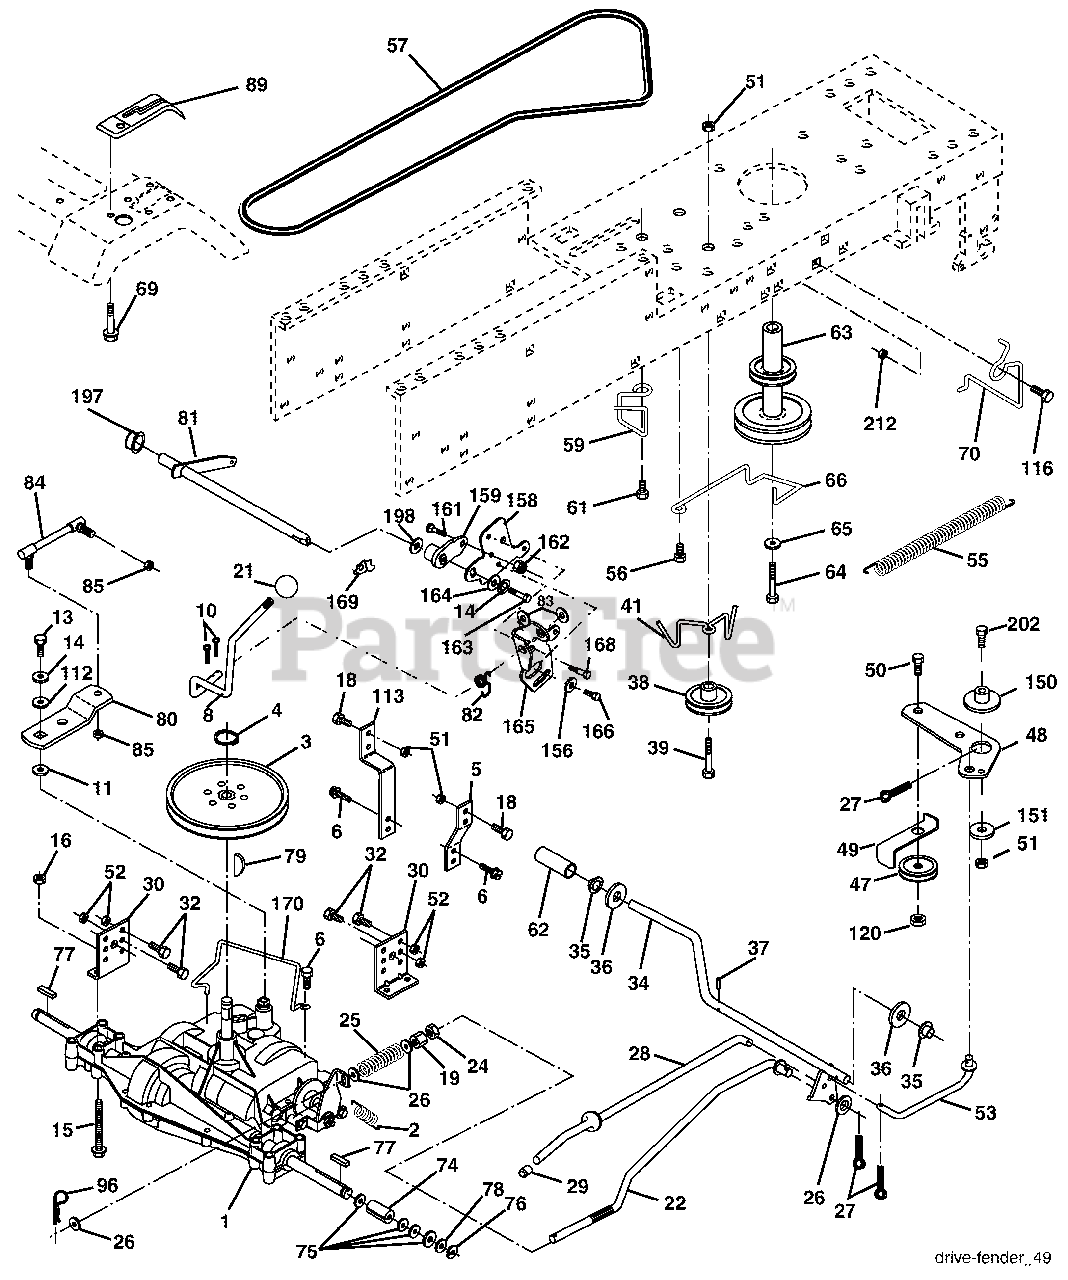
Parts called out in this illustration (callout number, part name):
2	Spring Return Brake T/a Zinc
3	Pulley Transaxle 18" tires
4	Ring Retainer #5100-62
5	Strap Torque 30 Degrees
6	Screw 5/16-18 X 3/4
8	Rod Shift Fender Adjust Lt
10	Pin Cotter 1/8 X 1 Cad
11	Washer Plate Shf 388 Sq Hole
13	Bolt 1/4-28 Unf Gr 8 W/Patch
14	Washer Lock Hvy Helical
15	Bolt Hex FLGHD 5/16-18 Gr. 5
16	Nut Lock Hex w/ins 5/16-18
18	Bolt, Fin Hex 3/8-16 UNC x 1 Gr. 5
19	Nut Lock 3/8-16 Unc
21	Knob
22	Rod Brake Blk Zinc 26 840
24	Nut Hex Jam 3/8-16 Unc
25	Spring Rod Brake 2 00 Zinc
26	Washer 13/32 X 13/16 X 16 Ga
27	Pin Cotter 1/8 X 3/4 Cad
28	Rod Brake Parking LT/YT
29	Cap Brake Parking
30	Bracket Mtg Transaxle
32	Bolt Hex Hd 5/16-18 unc X 3/4
34	Shaft Asm Pedal Foot
35	Bearing Nylon Blk 629 Id
36	Washer 21/32 X 1 X 16 Ga
37	Pin Roll 3/16 X 1"
38	Pulley Composite Flat
39	Bolt Fin Hex 3/8-16 unc X 3
41	Keeper Belt Flat Idler
47	Pulley Idler V Groove Plastic
48	Bellcrank Asm
49	Retainer Belt Style Spring
50	Bolt Carr. Sh. 3/8-16 x 1-1/2 Gr. 5
51	Nut Crownlock 3/8-16 Unc
52	Nut Crownlock 5/16-18 Unc
53	Link Clutch
55	Spring Return Clutch 6 75
56	Screw 3/8-16 x 1-1/4
57	V-Belt Ground Drive 95 25
59	Keeper Belt Span Ctr
61	Screw 3/8-16 x .875
62	Cover Pedal Blk Round
63	Engine Pulley
64	Bolt Hex
65	Washer Lock Hvy Hlcl Spr 7/16
66	Keeper Belt Engine Foolproof
69	Screw Hex wsh Hi Lo 1/4 x 1/2 unc
70	Guide Belt Mower Drive RH
74	Spacer Axle
75	Washer 25/32 X 1 1/4 X 16 Ga
76	E-ring #5133-75
77	Key Square 2 0 X 1845/ 1865
78	Washer 25/32 X 1-5/8 X 16 Ga
79	Key Woodruff #9 3/16 x 3/4
80	Arm Shift
81	Shaft Asm Cross Tapered PMST/20
82	Spring Torsion T/a
83	Washer 17/32 X 3/4 X 16 Ga
84	Link Transaxle PMST/18" Zinc
85	Nut Lock Center 1/4 - 28 FNTHD
89	Console Shift STLT
96	Retainer Spring 1"
112	Washer 9/32 x 3/4 x 10 Ga.
113	Strap Torque LT
116	Bolt Rdhd Sq Neck 3/8-16 x 1
120	Nut Lock Flg. 3/8-16 Unc
150	Spacer Retainer
151	Washer 13/32 x 2 x 10
156	Washer Srrted 5/16ID x 1.125
158	Bracket Shift Mount
159	Hub Tapered Flange Shift Lt
161	Bolt Rdhd Sqnk 1/4-20 x 3/4
162	Nut Crownlock 1/4-20 Unc
163	Bolt Hex Fin 1/4-20 Unc x 1 Gr. 5
164	Washer 9/32 x 3/4 x 10 Ga.
165	Bracket Pivot Lever
166	Screw 5/16-18 x 5/8
168	Bolt Shoulder 5/16-18 x .561
169	Plate Fastening
170	Keeper Belt Transaxle Gear
197	Nyliner Snap-In
198	Washer Nyliner
202	Bolt Rd Hd 3/8-16 Unc x 1-3/4 Gr. 5
212	Nut Hexflange Lock
